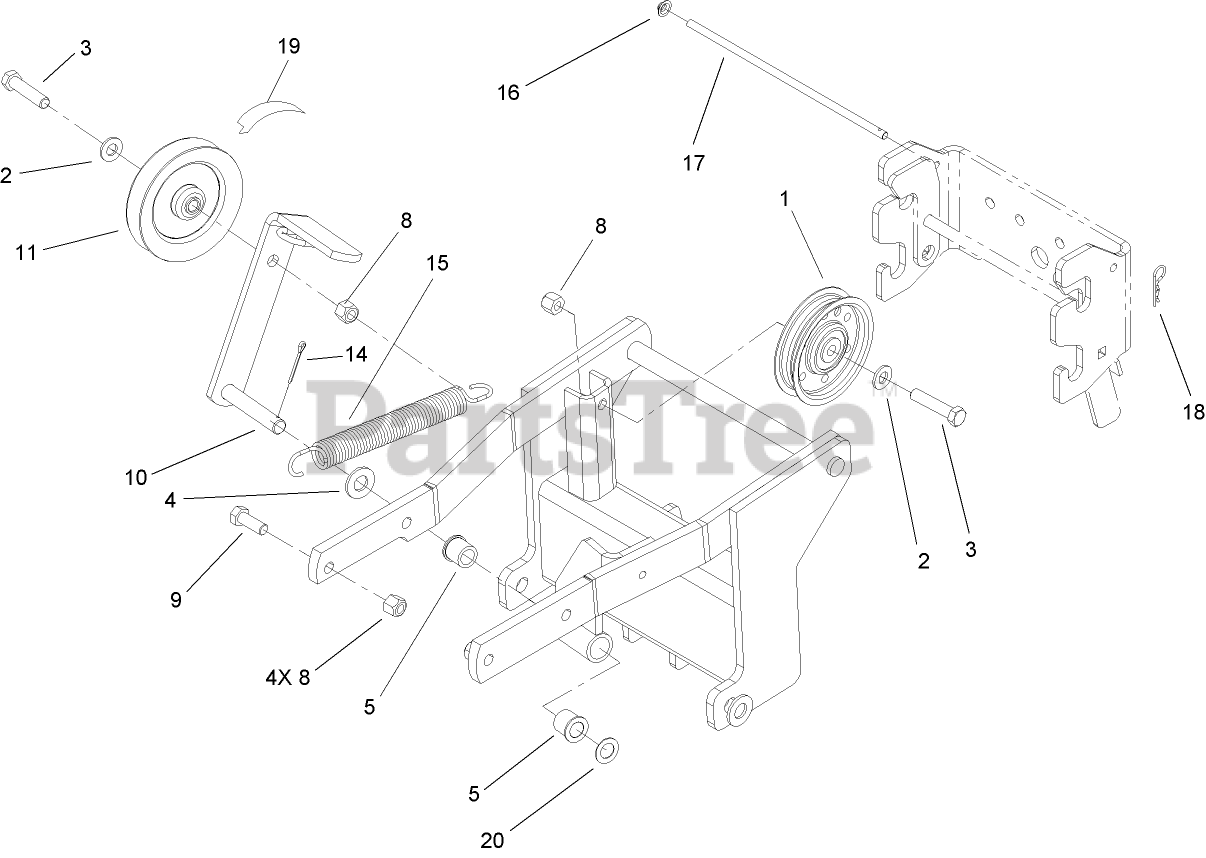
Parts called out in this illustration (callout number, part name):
1	PULLEY-IDLER, FLAT
2	WASHER-FLAT
3	SCREW-HH
4	WASHER-FLAT
5	BUSHING
8	NUT-LOCK, NI
9	SCREW-HH
10	IDLER ARM ASM
11	PULLEY-V, IDLER
14	PIN-COTTER
15	SPRING-EXTENSION
16	NUT-SPEED
17	ROD-STOP
18	PIN-HAIR
19	V-BELT, JACKSHAFT
20	WASHER
